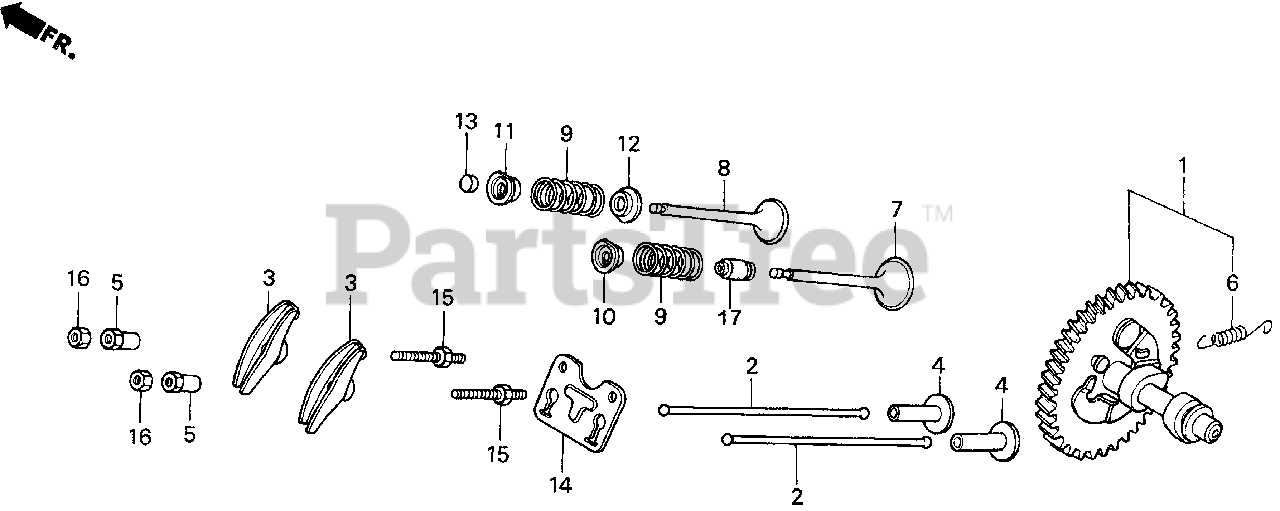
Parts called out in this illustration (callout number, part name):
1	CAMSHAFT ASSY.
2	ROD, PUSH
3	ARM, VALVE ROCKER
4	LIFTER, VALVE
5	PIVOT, ROCKER ARM
6	SPRING, WEIGHT RETURN
7	VALVE, IN.
8	VALVE, EX. (STELITE)
9	SPRING, VALVE
10	RETAINER, IN. VALVE SPRING
11	RETAINER, EX. VALVE SPRING
12	SEAT, VALVE SPRING
13	ROTATOR, VALVE
14	PLATE, PUSH ROD GUIDE
15	BOLT, PIVOT (8MM)
16	NUT, PIVOT ADJ.
17	SEAL, VALVE STEM
